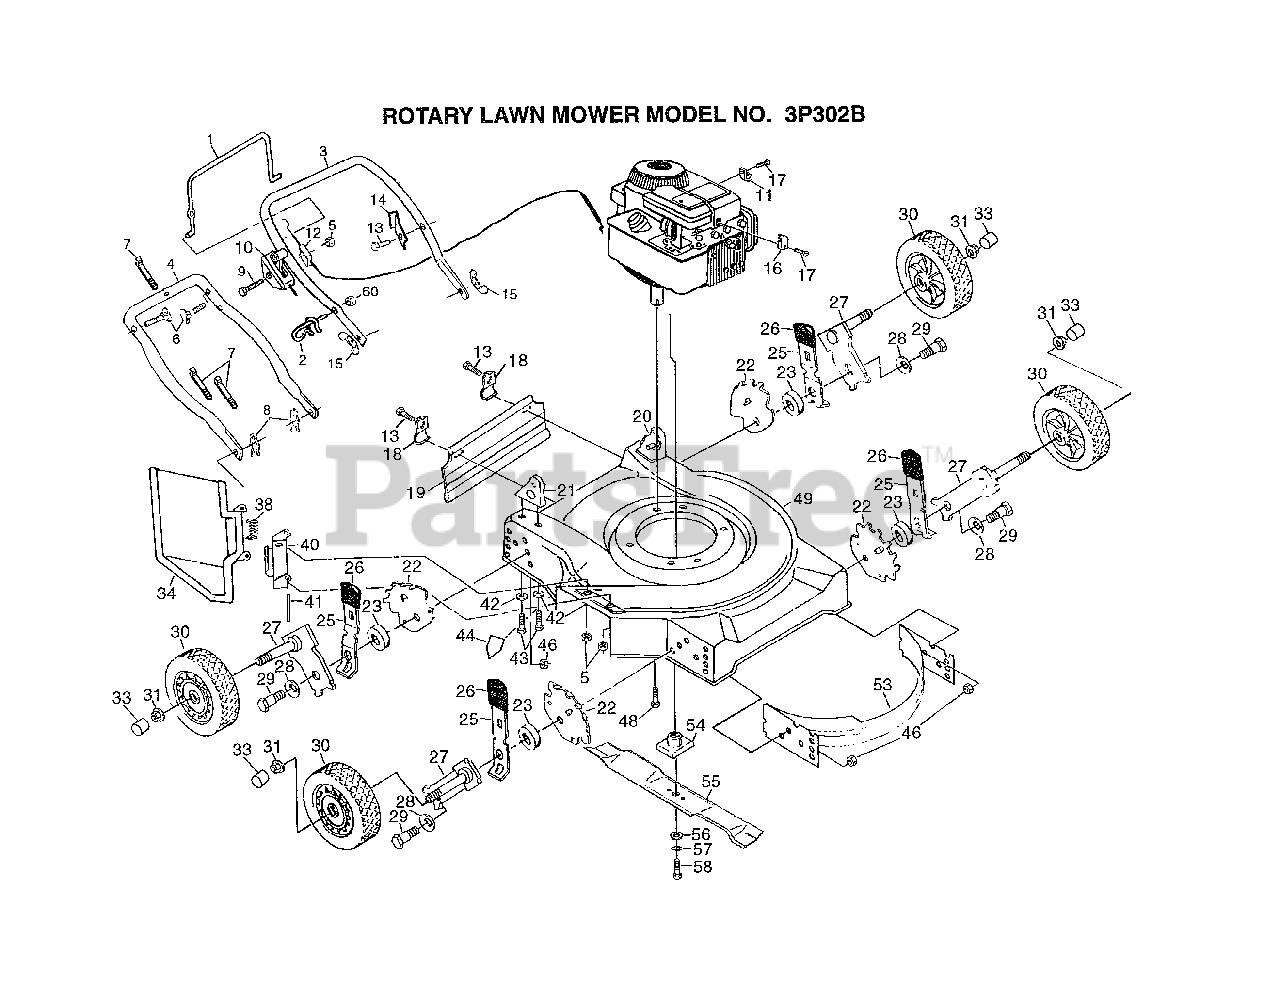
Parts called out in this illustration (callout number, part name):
1	CONTROL BAR
2	ROPE GUIDE
6	BOLT.HANDLE.LM
8	HAIRPIN COTTER
9	SCREW.HXHD.WASH.
10	CONTROL THROTTLE
11	GUIDE CLIP PM
12	"CABLE,ENG ZONE CO"
13	TAPPING SCREW
14	"BRKT,UPSTOP"
15	"NUT,WING PM"
16	CABLE CLAMP
17	SCREW PM
18	"BRKT,DEFL PM"
19	SKIRT.REAR.22SD.
22	BRACKET.ADJ.9POS.
25	SPRING SELECTOR
26	KNOB PM
27	ARM.AXLE.ASM.BZP.
28	"WASHER, BELLEVIL."
29	BOLT SHLD 3/8-16
30	WHEEL.ASM
31	HEX FLANGE LOCKNT
33	HUB CAP-PLASTIC
34	GUARD.DISCH.22SD.
40	BRACKET.HINGE.W/F
41	ROD.HINGE.COMBI-C
42	STEEL WASHER
43	SCREW
44	DECAL HYT
46	LOCKNUT PM
48	SCREW
49	KIT.HSG.22SD.PUSH
53	BAFFLE.FRT/REAR
54	BLADE ADAPTOR
55	"BLADE.MULCH.22"""
56	"WASHER,HARDEN"
57	LOCKWASHER
58	SCREW
60	NUT
